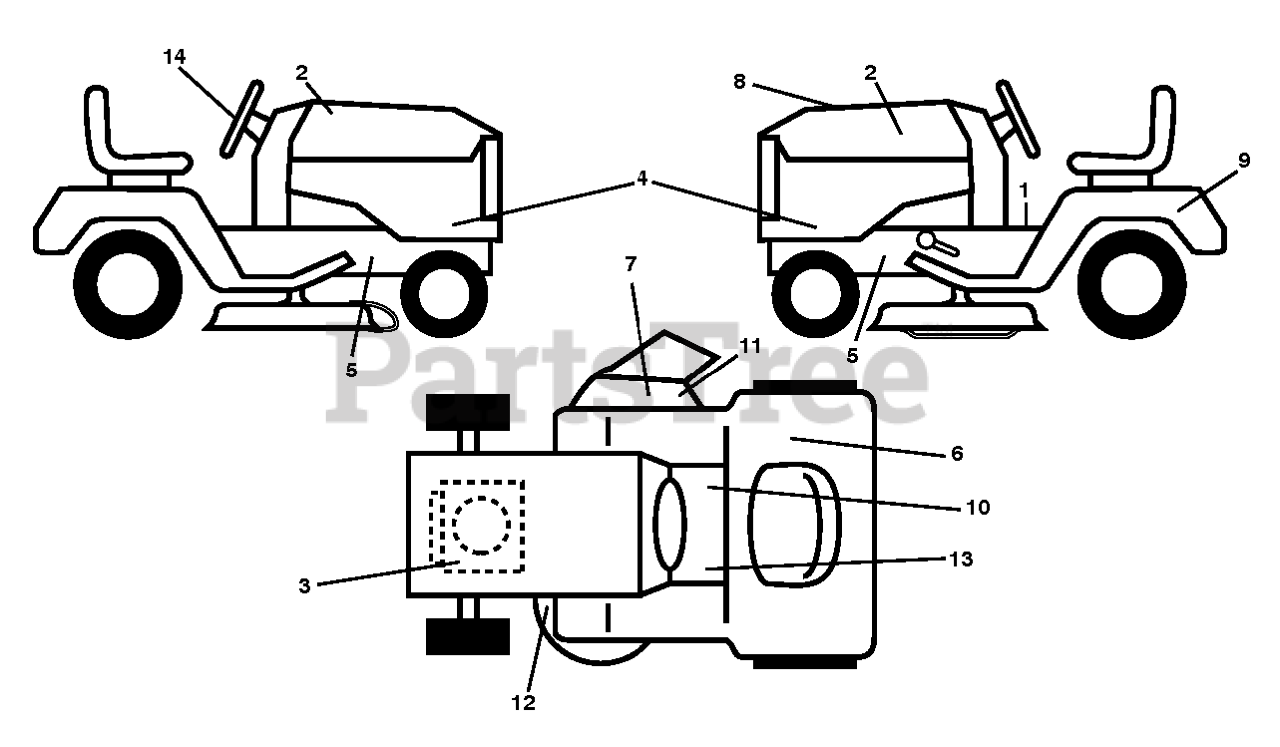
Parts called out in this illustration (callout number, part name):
1	LABEL
2	DECAL.HOOD.NAMELOGO.HUSQ
3	DECAL
6	Decal, Fender 100 DB/CE
7	DECAL.INTERNATIONL.CUTFINGER
9	DECAL BTRY SYMBOLS
10	DECAL PARK BRAKE
11	DECAL, DEFLECT WARNING
12	DECAL.V-BELT.SCHEMATIC.36/38/9
13	DECAL
14	DECAL.WHEEL.STRG.LGN.H
